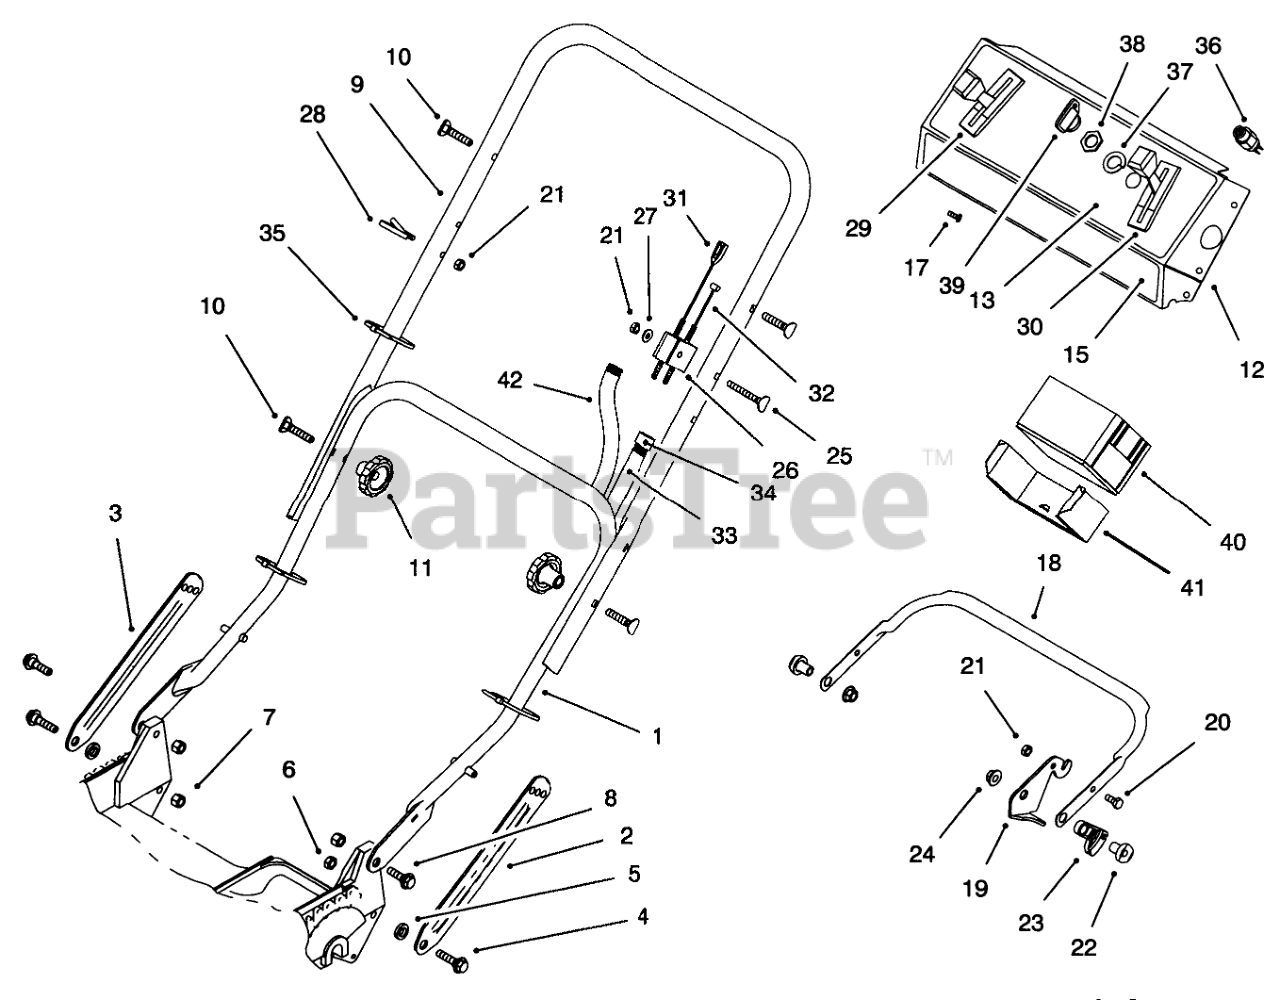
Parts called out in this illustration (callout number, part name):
1	ASM-Handle
2	Latch-Handle
3	Latch-Handle
4	SCREW-SHOULDER
5	SPACER
6	NUT-LOCK, NI
7	NUT-LOCK, NI
8	SCREW-SHOULDER
9	Handle-Upper
10	SCREW-HANDLE
12	Panel-Control (Incl. Ref. #13)
13	DECAL - CONSOLE
15	DECAL - CONSOLE
17	SCREW-TAP
18	Bar-Control
19	Lever-Control
20	SCREW-HH
21	NUT-LOCK, NI
22	SPACER-SUPPORT
23	LEVER-TRACTION
24	NUT-LOCK NI
25	SCREW-HANDLE
26	SUPPORT-CABLE
27	WASHER-FLAT
28	GUIDE-ROPE
29	CONTROL-SPEED, GROUND
30	CABLE - THROTTLE
31	CABLE - BRAKE
32	CABLE-TRACTION
33	CONTROL CABLE COVER
34	FITTING-RING
35	TIE-CABLE
36	Switch-Starter (Incl. Ref. #37 & 38)
37	WASHER-TOOTH, INTERNAL
38	NUT-HH
39	KEY-IGNITION
40	BATTERY ASSEMBLY
41	Retainer-Battery
42	WIRING HARNESS
